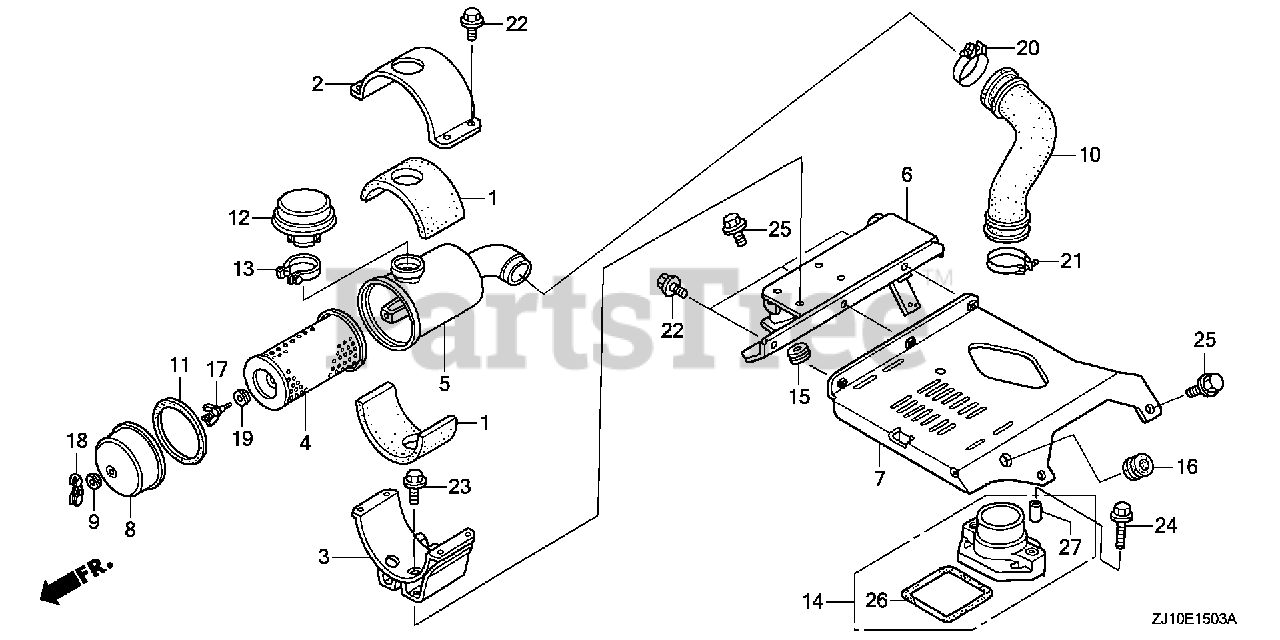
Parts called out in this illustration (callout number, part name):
1	RUBBER, AIR CLEANER HOLDER (UPPER)
2	HOLDER, AIR CLEANER (UPPER)
3	HOLDER, AIR CLEANER (LOWER)
4	ELEMENT, AIR CLEANER
5	HOUSING, AIR CLEANER (SNORKEL)
6	STAY A, AIR CLEANER (SNORKEL)
7	STAY B, AIR CLEANER (SNORKEL)
8	COVER, AIR CLEANER
9	GROMMET, AIR CLEANER
10	TUBE, AIR CLEANER CONNECTING
11	SEAL, AIR CLEANER
13	CLAMP ASSY.
14	JOINT ASSY., CONNECTING TUBE (B)
15	GROMMET, RESERVE TANK
17	BOLT, AIR CLEANER
18	WINGNUT (6MM) (BLACK)
19	WASHER, AIR CLEANER
20	BAND, AIR CLEANER CONNECTING TUBE (50)
20	BAND, AIR CLEANER CONNECTING TUBE (52)
21	BAND, AIR CLEANER CONNECTING TUBE (58)
22	BOLT, FLANGE (6X12)
23	BOLT, FLANGE (6X16)
24	BOLT, FLANGE (6X28)
25	BOLT, FLANGE (8X20)
26	SEAL, AIR CLEANER HOUSING
27	COLLAR A, AIR CLEANER
